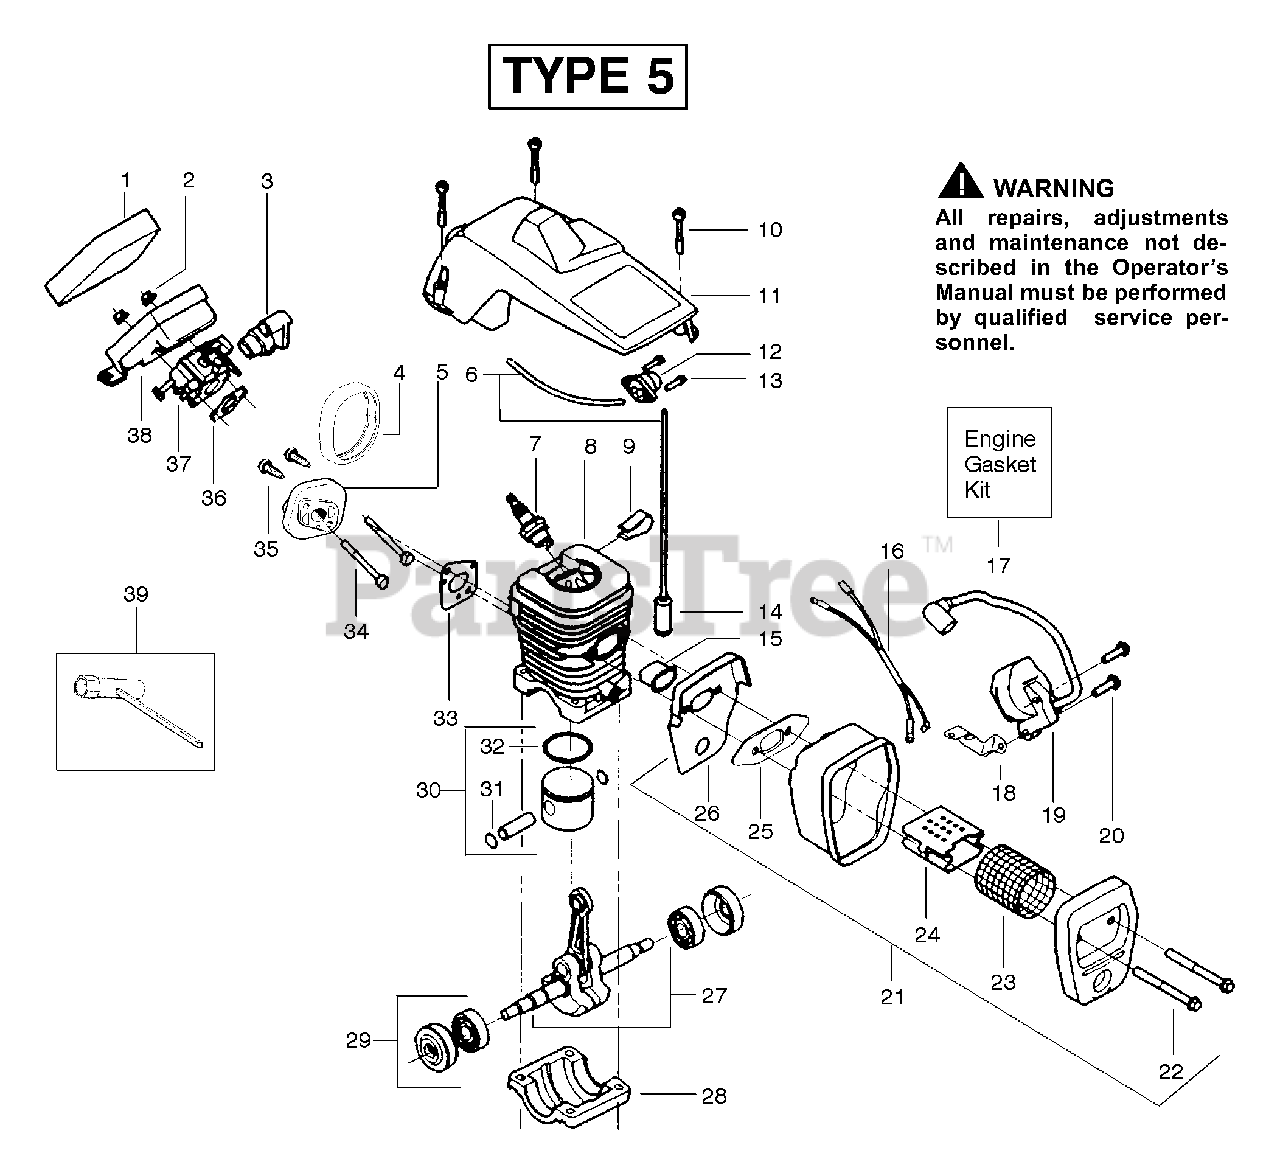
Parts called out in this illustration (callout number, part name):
1	Foam Air Filter
3	Grommet Carb Adjust
4	Seal Carb Adapter
5	Adapter Carb.
6	Kit Fuel Line (Small)
7	Spark Plug (RCJ7Y)
8	Kit Cylinder
9	Clip High Tension Lead
11	Shield Cylinder
12	Assy Air Purge
14	Assy Fuel Pickup
15	Insulator Heat
16	Assy. Wire Harness
17	Kit Engine Gasket
18	Strap Ground
19	Module Ignition
21	Assy Muffler
23	Screen Spark
24	Diffuser Muffler
25	Gasket Muffler (kit)
26	Backplate Muffler
27	Assy. Crankshaft
28	Cap Crankcase
29	Assy. Seal & Bearing
30	Kit Piston
31	Retainer Piston Pin
32	Ring Piston
33	Gasket Adapter (kit)
36	Gasket Carb. (kit)
37	Kit Carburetor (W-14A)
38	Housing Air Filter
39	Wrench Bar
